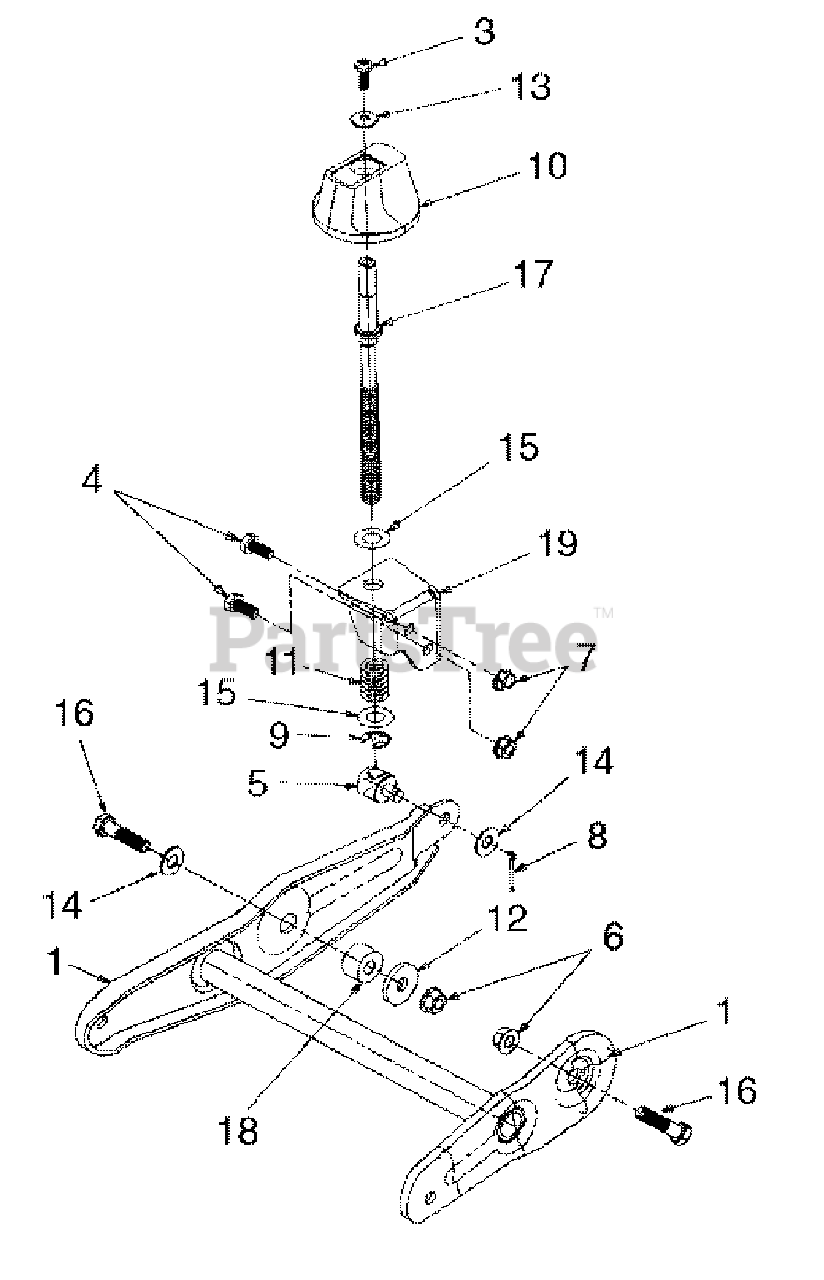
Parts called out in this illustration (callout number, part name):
1	Bracket Ass'y, Wheel Pivot
3	Screw, Pan Hd Mach, 1/4-20 x .75
4	Screw, Hex Cap, 5/16-18 x .75 GR5
5	Ferrule, Adjustment
6	Nut, Hex Flange Lock, 3/8-16
7	Nut, Hex Flange Lock, 5/16-18
8	Pin, Cotter, 1/8 x 1.0
9	E-Ring, .50 Dia
11	Spring, Compression
12	Washer, Flat, .406 x 1-1/4
13	Washer, Bell, .265 x .75 x .062
14	Washer, Flat, .406 x .875 x .059
15	Washer, Flat, .508 x 1.0 x .020
16	Shoulder Bolt, .75 x .43: 3/8-16
17	Rod, Height Adjustment
18	Spacer, .380 ID x 1.0 OD x .32 Lg
19	Bracket, Height Adj
